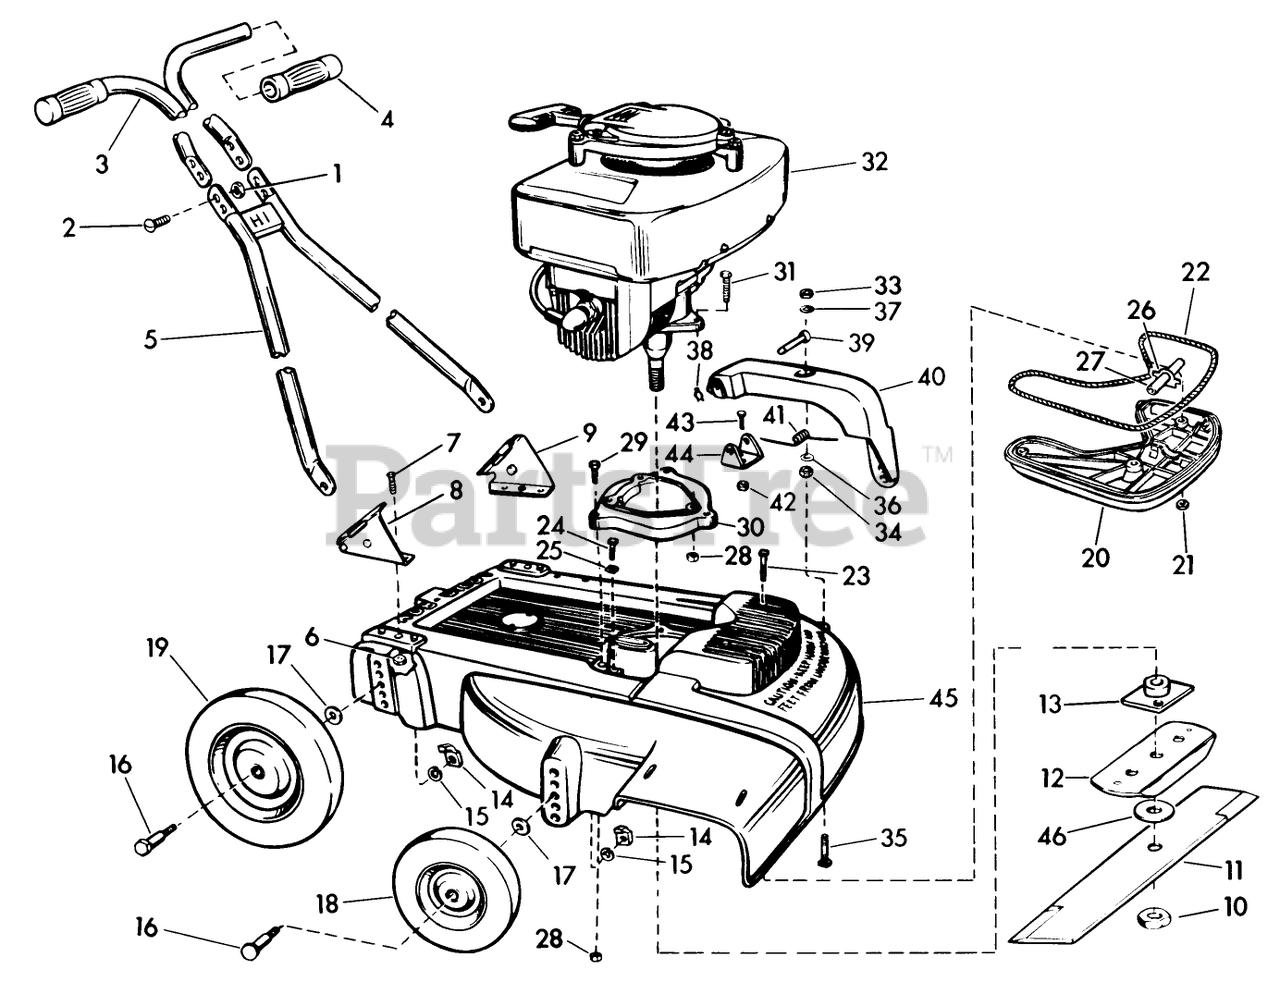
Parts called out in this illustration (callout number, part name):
1	STOP NUT
10	NUT-BLADE
11	Blade-21"
13	PLATE AND COLLAR ASM
15	WASHER, LOCK
21	LOCKNUT E
24	Bolt-Muffler
25	Gasket-Muffler Bolt
26	Gasket-Internal Tube
27	Tube-Internal Muffler
29	Screw-Sub Base Mounting
30	Sub Base
33	STOP NUT
34	Nut-Level-Ride Bolt
35	Bolt-Level-Ride Arm
36	Washer-Level Ride Arm
37	Washer-Level Ride, Fiber
38	Hair Pin-Level Ride Arm
39	Pin-Level Ride Arm
40	Arm-Level Ride
41	Spring-Level-Ride Arm
42	STOP NUT
43	Screw-Level-RideArm Bracket
44	Bracket-Level Ride Arm
45	Housing-18" Model 5210
45	Housing-21" Model 7210
